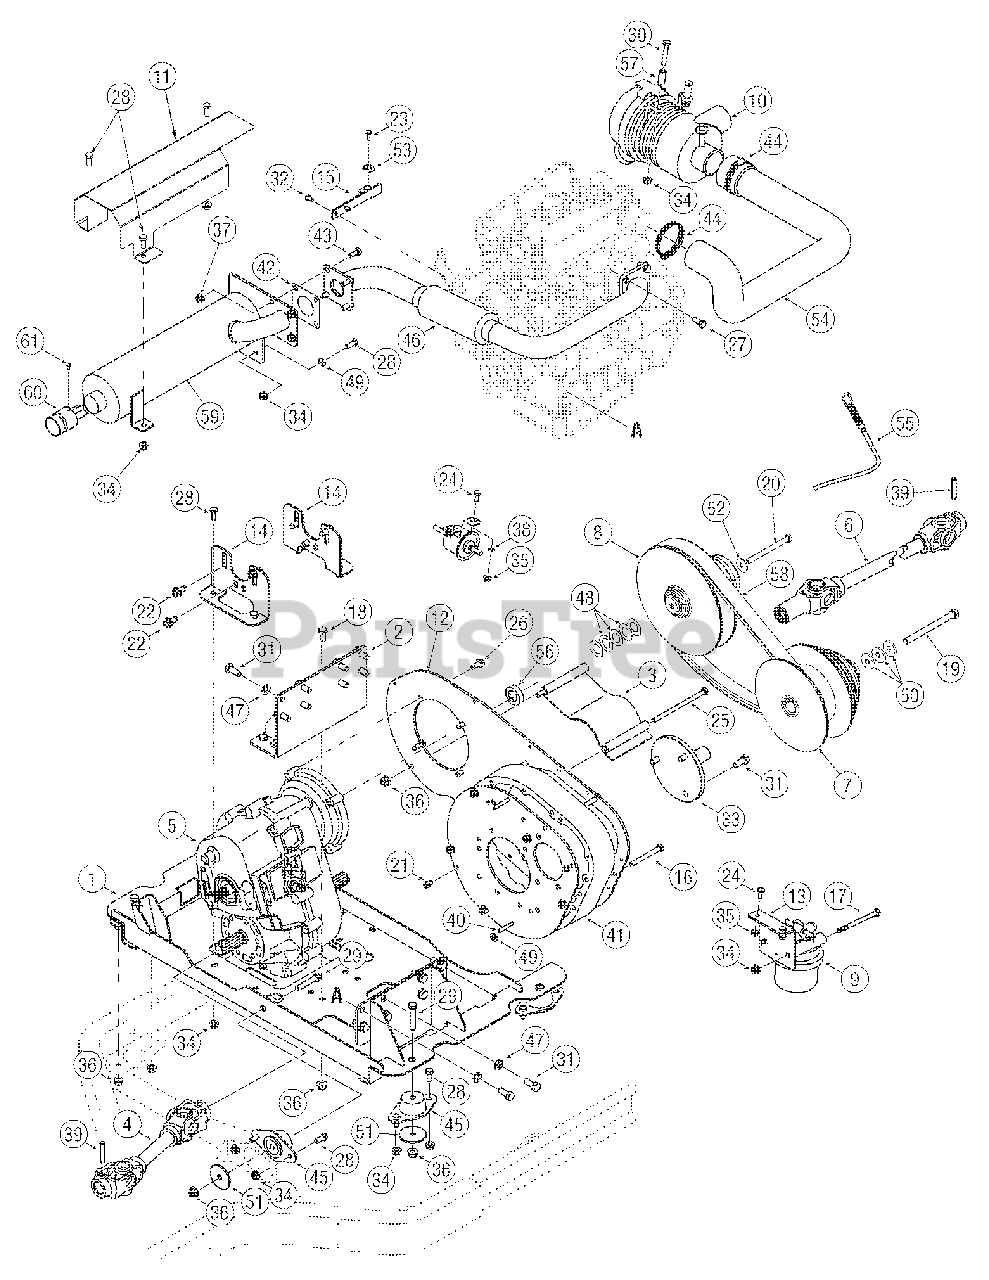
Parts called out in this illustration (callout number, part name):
5	Case Assembly, transfer
6	Shf Assembly, frt/prop, Hilliard
7	Clu Assembly, Cvt, Driver, Cat
8	Clu Assembly, cvt, driven
9	Filter, Assembly, Diesel
10	Filter, Assembly, Aircl, 4x4, Cat
11	Shield, Exhaust Heat
13	Screw, 3/8-24, 4.50, Gr5,
15	Mt, Cbl, Throt, Cat
16	Screw, 5/16-18, 3.00, gr5, std
17	Screw, 5/16-18, 4.00, gr5, std
18	Screw, 3/8-16, .75
19	Screw, 7/16-20, 5.00, gr5, std
20	Screw, 3/8-16, 4.25 Gr5
21	Screw, TT, 1/4-20, .500
22	Scr, tt, 3/8-16, 0.750, hxindwsh
23	Screw, SF, #10-24, .625
24	Screw, 1/4-20, .620
25	Screw, 5/16-18, 5.25, gr5, std
26	Scr, ld, 5/16-18, 0.750, hxindwsh
27	Screw, MB-1.25, 20.00
28	Screw, 5/16-18, .75, gr5, std
29	Screw, 3/8-16, 2.00, gr5, std
30	Screw, 5/16-18, 1.75
31	Screw, M10-1.5, 25mm
32	Screw, M6-1.0, 10mm
33	Shaft, Output, Cat, Tapered
34	Nut, flglk, 5/16-18, grf, nylon
35	Nut, flglk, 1/4-20, grf, nylon
36	Nut, flglk, 3/8-16, grf, nylon
37	Nut, flglk, 5/16-18, gr5, sd Lk
38	Washer, Lock, 1/4
39	Pin, spirol, 5/16, 1.75
40	Spring, Pin, .25 Dia. x 2.50 Spiral
41	Spcr, eng/trans Plt, mount
42	Gskt, eng, 4x4
43	Screw, 5/16-18 x .875
44	Clamp, Hose, Adj. 2-3"
45	Mt, comprs, eng, hd
46	Pipe, Exh, Cat, 4x4
47	Wash, Lock, 7/16, Regular Duty
48	Wash, Flat, .793 x 1.368 x .025 ht
49	Wash, flat, .330 X .630 X .0635
50	Wash, flat, .450x1.250x.164, ht
51	Wash, flat, .38 X 2.00 X .12
52	Wash, Bell, .396 x 1.14 X .095
53	Clamp, Casing
54	Hose, Air inlet, Cat 4x4
55	Cbl, cont, throt, Cat
56	Spcr, 20mm X 1.50 X .37
57	Spcr, 5/16 ID x .49 x 1.015 Lg
58	Belt, cvt, 4x4
59	Mflr, 4x4, Cat/Khlr
60	Arstr, spark
61	Screw, Hex #8-32 x .375
